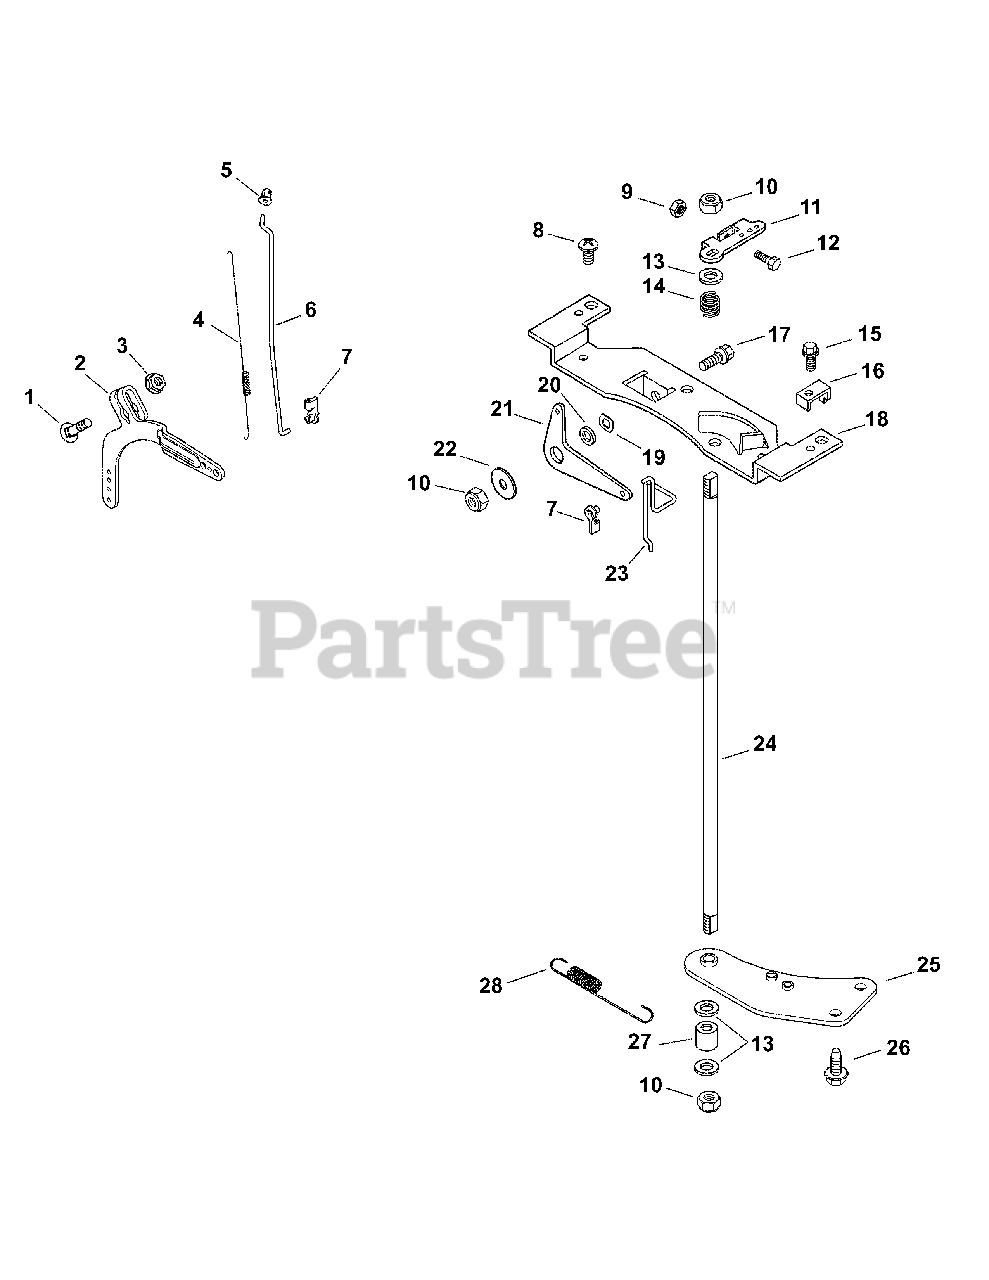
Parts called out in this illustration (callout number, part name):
1	Bolt, Rd Hd Sq Neck M6 x 1.0 x 25
2	Lever, Governor
3	Nut, FLG M6 x 1.0
4	Spring, Linkage
5	Bushing, Linkage Retaining
6	Linkage, Throttle
7	Bushing, Throttle Linkage
8	Screw, Phl Hd 11-16 x 3/4"
9	Nut, M4 x 0.7
10	Nut, Lock M6 x 1.0
11	Lever, Throttle Control
12	Screw, Cap M4 x 0.7 x 30
13	Washer, Flat 1/4"
14	Spring, Throttle Shaft
15	Screw, Flg Thd Frm M5 x 0.8 x 16
16	Clamp, Cable
17	Screw, Flg M6x1.0x16
18	Bracket, Control
19	Washer, Spring 3/8"
21	Lever, Choke
22	Washer, Flat 1/4"
23	Linkage, Choke
24	Shaft, Throttle
25	Bracket, Throttle Shaft
26	Screw, Flg Thd Frm M6 x 1.0 x16
28	Spring, Governor
